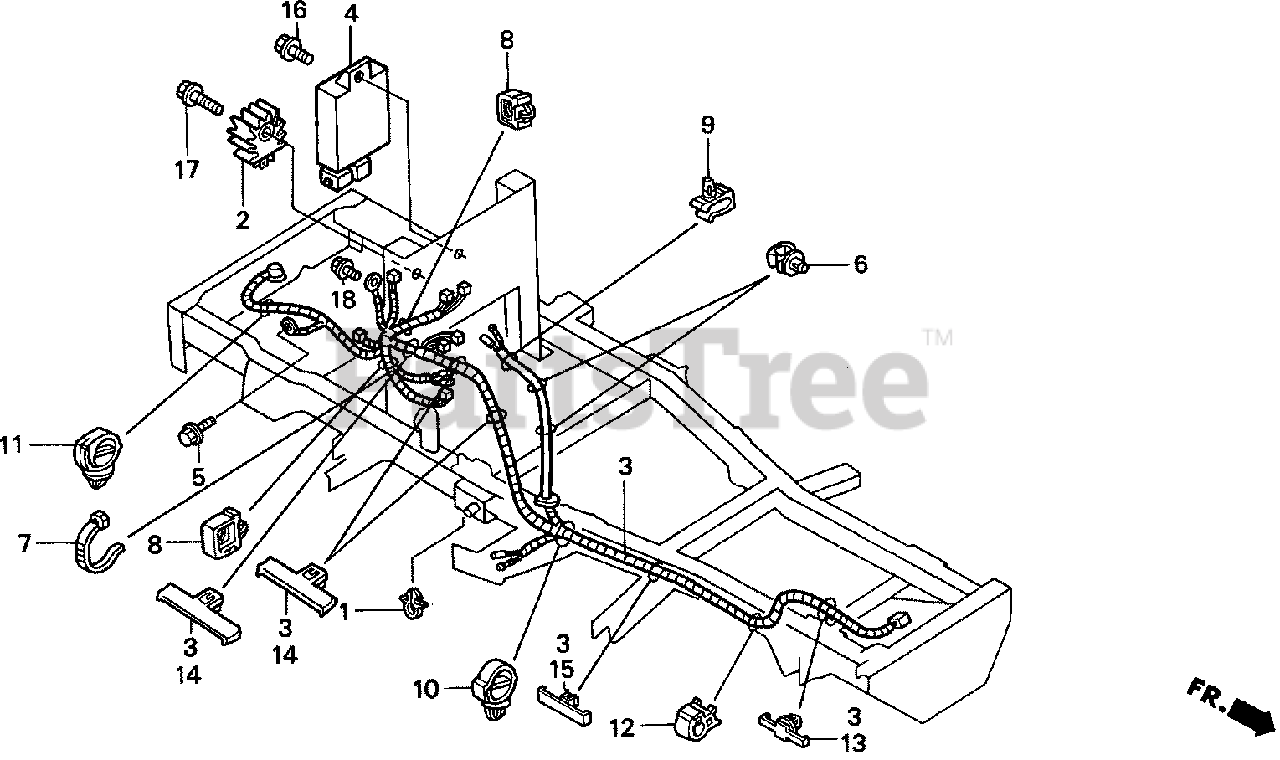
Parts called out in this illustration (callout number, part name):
1	CLIP, IGNITION WIRE
2	RECTIFIER, REGULATE
2	RECTIFIER, REGULATOR (5A)
3	WIRE HARNESS ASSY., MAIN (NOT AVAILABLE)
3	WIRE HARNESS ASSY., MAIN
4	RELAY ASSY., COMBINATION
5	BOLT, GROUND (6X12)
6	CLIP, WIRE HARNESS
8	CLIP, HARNESS (10MM)
9	CLIP, CORD
10	CLIP, WIRE HARNESS
11	CLIP, WIRE HARNESS (25MM)
12	CLIP, CABLE (8MM)
13	CLIP, WIRE HARNESS (50MM) (GRAY)
14	CLIP, WIRE HARNESS
15	CLIP, WIRE HARNESS (BLACK)
16	BOLT, FLANGE (6X12)
17	BOLT, FLANGE (6X30)
18	BOLT, FLANGE (8X16)
